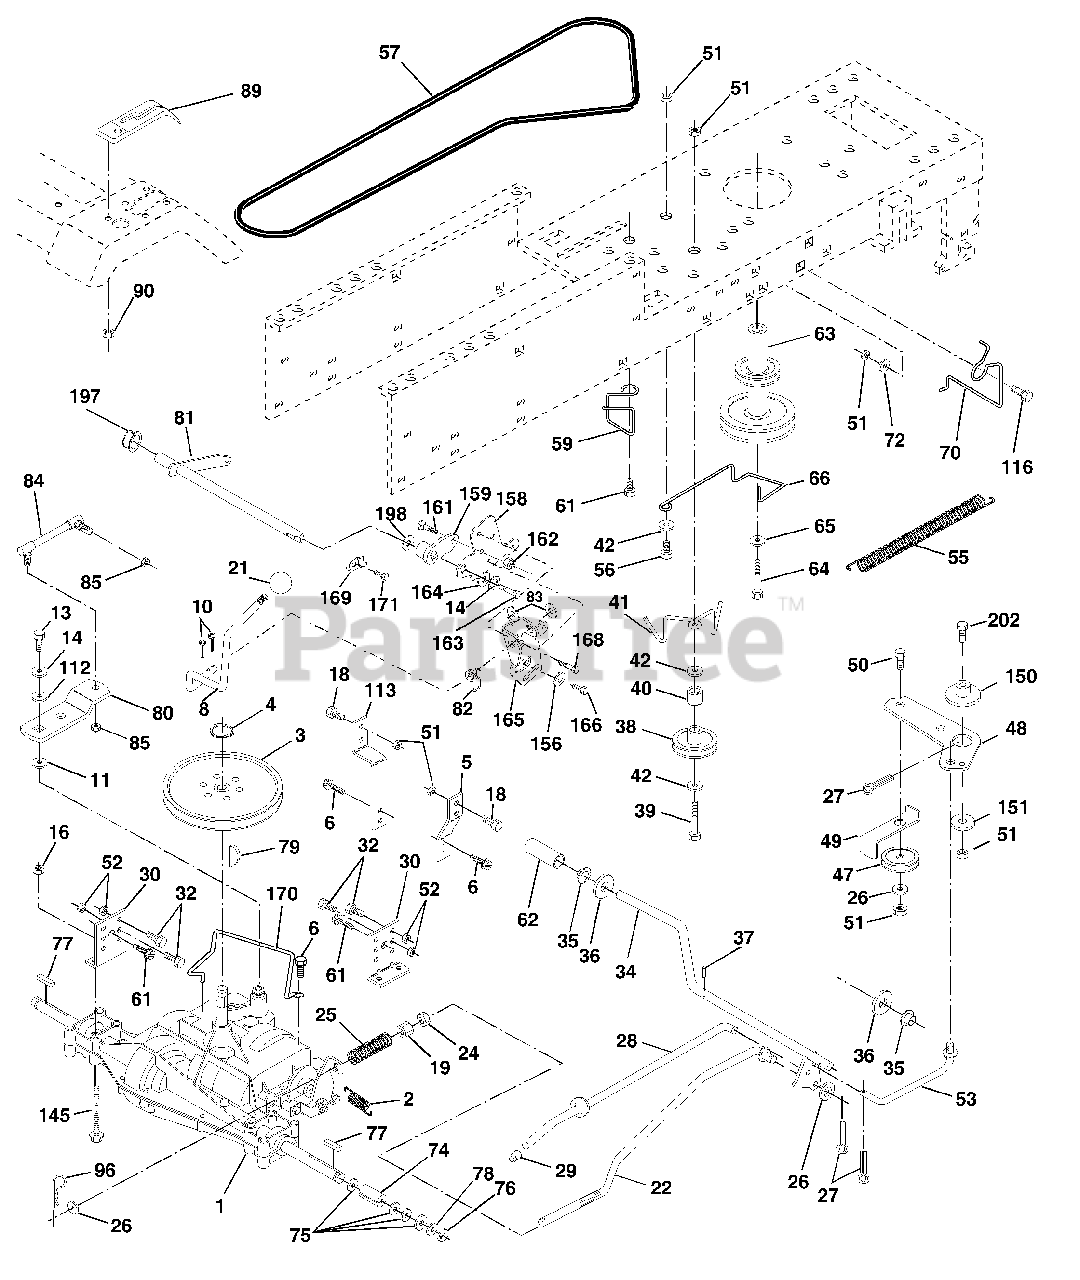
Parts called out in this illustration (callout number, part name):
2	Spring Return Brake T/a Zinc
3	Pulley Transaxle 18" tires
4	Ring Retainer #5100-62
5	Strap Torque 30 Degrees
6	Screw 5/16-18 X 3/4
8	Rod Shifter Fender Adj Lt
10	Pin Cotter 1/8 X 1 Cad
11	Washer Plate Shf 388 Sq Hole
13	Bolt 1/4-28 Unf Gr 8 W/Patch
14	Washer Lock Hvy Helical 1/4
16	Nut Lock Hx W/Ins 5/16-18unc
18	Bolt, Fin Hex 3/8-16 UNC x 1 Gr. 5
19	Nut Lock 3/8-16 Unc
21	Knob
22	Rod Brake Blk Zinc 26 840
24	Nut Hex Jam 3/8-16 Unc
25	Spring Rod Brake 2 00 Zinc
26	Washer 13/32 X 13/16 X 16 Ga
27	Pin Cotter 1/8 X 3/4 Cad
28	Rod Brake Parking LT/YT
29	Cap Brake Parking
30	Bracket Mtg Transaxle
32	Bolt Hex Hd 5/16-18unc X 3/4
34	Shaft Asm Pedal Foot
35	Bearing Nylon Blk 629 Id
36	Washer 21/32 X 1 X 16 Ga
37	Pin Roll 3/16 X 1"
38	Pulley Idler Flat
39	Bolt Fin Hex 3/8-16unc X 2-3/4
40	Spacer Split 395 X 59 Bzp
41	Keeper Belt Retainer Idler
42	Washer 13/32 X 13/16 X 12 Ga
47	Pulley Idler V Groove Plastic
48	Bellcrank Asm
49	Retainer Belt Style Spring
50	Bolt Hex Hd 3/8-16unc X 1-1/2
51	Nut Crownlock 3/8-16 Unc
52	Nut Crownlock 5/16-18 Unc
53	Link Clutch
55	Spring Return Clutch 6 75
56	Bolt Fin Hx 3/8-16 X 1-1/4
57	V-Belt Ground Drive
59	Keeper Belt Span Ctr
61	Screw 3/8-16 x 3/4
62	Cover Pedal Blk Round
63	Engine Pulley LT/YT
64	Bolt Hex
65	Washer Lock Hvy Hlcl Spr 7/16
66	Keeper Belt Engine Foolproof
70	Guide Belt Mower Drive RH
72	Washer 13/32 X 1-1/4 X 12 Ga
74	Spacer Axle
75	Washer 25/32 X 1 1/4 X 16 Ga
76	E-ring #5133-75
77	Key Square 2 0 X 1845/ 1865
78	Washer 25/32 X 1-5/8 X 16 Ga
79	Key Woodruff
80	Arm Shift
81	Shaft Asm Cross Tapered 20"t
82	Spring Torsion T/a
83	Washer 17/32 X 3/4 X 16 Ga
84	Link Transaxle
85	Nut Lock Center 1/4 - 28 FNTHD
90	Nut Self-thd Wsh-hd 1/4 Zinc
96	Retainer Spring
112	Washer 9/32 x 3/4 x 10 Ga.
113	Strap Torque Lh
116	Bolt Rdhd Sq Neck 3/8-16 x 1.25
145	Bolt Hex 5/16-18 Gr. 5
150	Bushing Bellcrank Grd. Drive
151	Washer 13/32 x 2 x 10
156	Washer Srrted 5/16 ID x 1.125
158	Bracket Shift Mount
159	Hub Tapered Flange Shift lt
161	Bolt Rdhd Sqnk 1/4-20 x 3/4 Gr 5
162	Nut Crownlock 1/4-20 Unc
163	Bolt Hex Fin 1/4-20 Unc x 1 Gr 5
164	Washer 5/8 x .281 x 10 Ga
165	Bracket Pivot Lever
166	Screw 5/16-18 x 5/8
168	Bolt Shoulder 5/16-18 x .561
169	Plate Fastening Lt
170	Keeper Belt Transaxle Pmst/Dana
171	Screw Thdrol 3/8-16 x 1/2 TY-TT
197	Nyliner Snap-In
198	Washer Nyliner
202	Bolt Carr. Sh 3/8-16 x 1-1/2 Gr. 5
